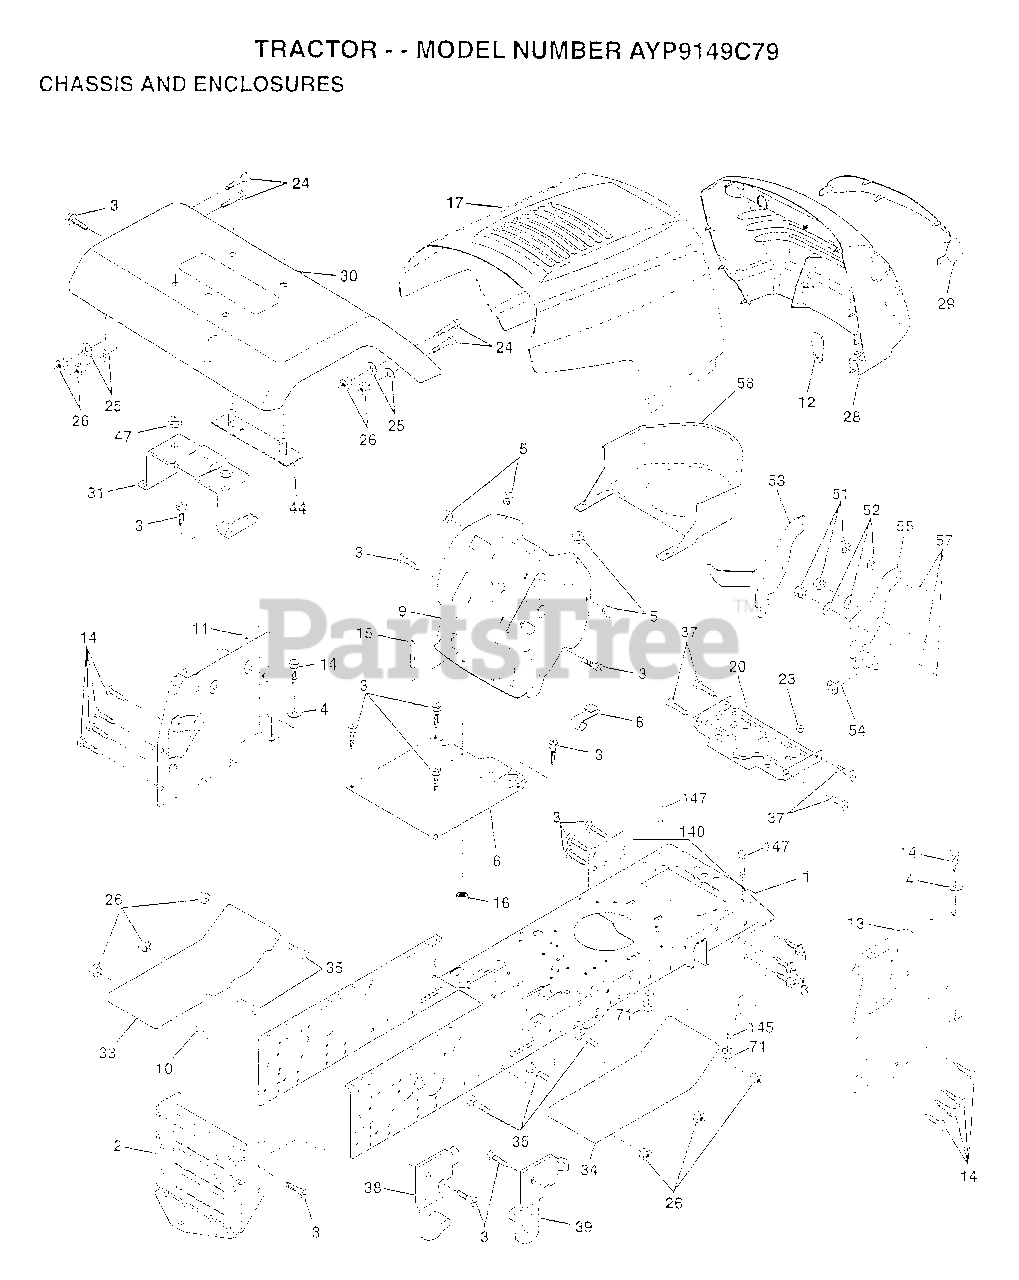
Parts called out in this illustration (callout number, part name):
1	CHASSIS ASM
3	SCREW
4	WASHER
5	BUMPER-HOOD/DASH
6	SADDLE
8	CLIP.RETAINER
9	DASH.SILKSCREENED
11	"PANEL-DASH,LH"
12	CLIP.TINNERMAN
14	SCREW LT
15	SCREW
20	"PLATE-MTG,BATT/FU"
24	BOLT
25	WASHER
26	NUT
28	GRILLE-MS428
29	LENS GRILLE
31	BRKT FENDER
33	FOOTREST LH
34	FOOTREST RH
35	BOLT
37	SCREW LT
38	BRACKET ASM LH
39	BRACKET ASM RH
51	NUT
52	WASHER
53	BRACKET.GRILLE.LH
55	BRACKET.GRILLE.RH
58	AIR DUCT
140	BRKT SUSPENSION
145	"ROD POVOT,CHASSIS"
147	BOLT LT
